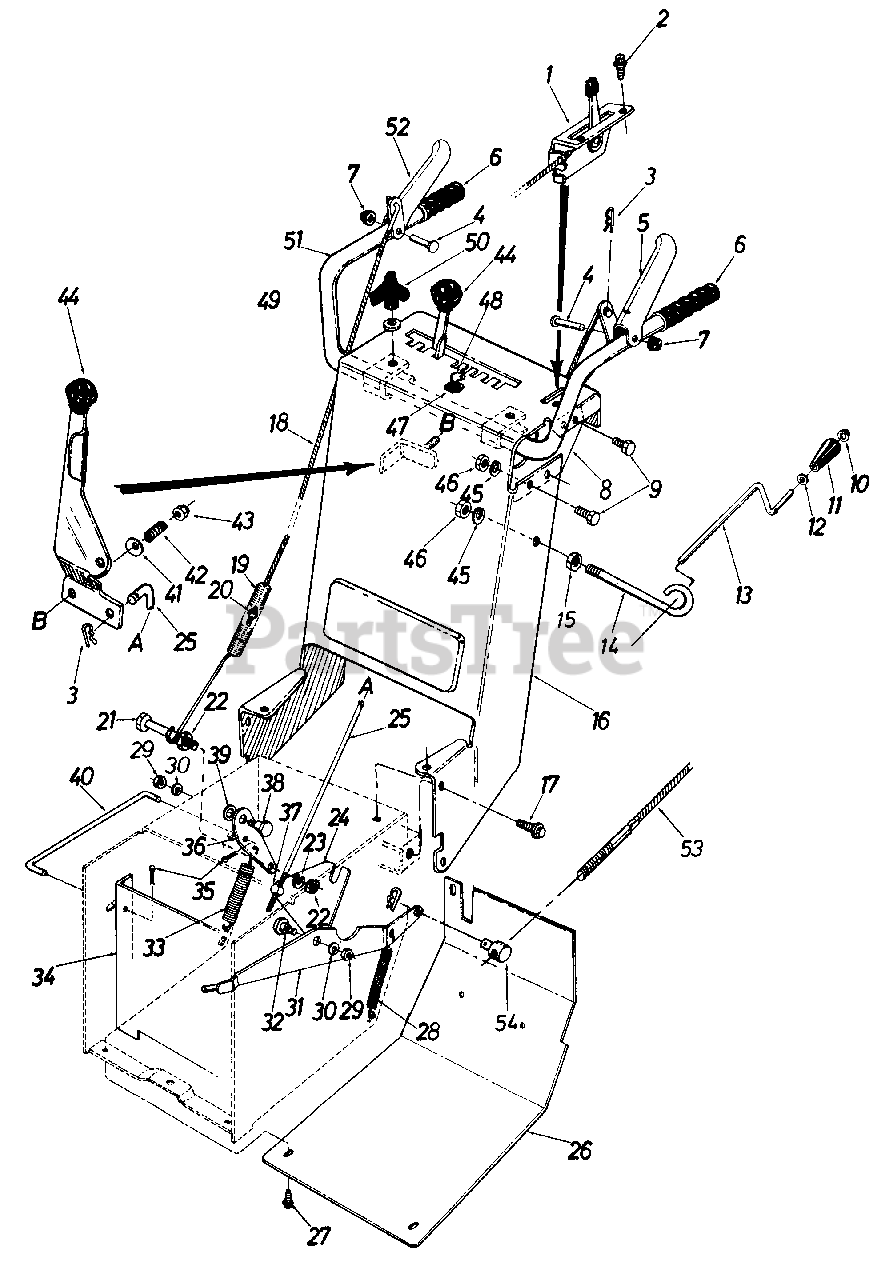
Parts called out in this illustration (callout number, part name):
1	Throttle Control Ass'y. Comp.
2	Hex AB-Tap Scr. #8 x .50" Lg.
3	Hairpin Cotter
4	Clevis Pin .375" Dia. x 1.88" Lg.
5	Auger Clutch Grip Ass'y. - L.H.
6	Grip Handle
7	Push Cap .375 Rod - Black
8	Handle Support Brkt.
9	Hex Bolt 5/16-24 x .62" Lg.
10	Push Nut 3/8" Rod
11	Knob 3/8" I.D.
12	Fl-Wash. .385 I.D. x .62 O.D. .063
13	Chute Crank .38 Dia. x 41" Lg.
14	Chute Control Support Rod
15	Hex Nut 5/16-18 Thd.
16	Handle Panel Ass'y.
17	Hex Wash. Self-Tap Scr. 5/16-24 x .50" Lg.
18	Lockout Cable - 30.5" Lg.
19	Spring .750 O.D. x 5.0" Lg.
20	Hex Ins. L-Nut 1/4-20 Thd.
21	Hex Bolt 1/4-28 x 2.5" Lg.
22	Hex Nut 1/4-28 Thd.
23	L-Wash. 1/4" I.D.
24	Shifting Linkage Brkt.
25	Shifting Rod
26	Frame Cover
27	Hex Wash. Self-Tap Scr. 1/4-20 x .50 Lg.
28	Ext. Spring .38" O.D. x 3.25" Lg.
29	Hex Jam Nut 3/8-16 Thd.
30	L-Wash. 3/8-16 I.D.
31	Auger Clutch Brkt. Ass'y.
32	Shld. Bolt .625" Dia. x .170" Lg.
33	Idler Extension Spring
34	Drive Pulley Support Brkt. Ass'y.
35	Cotterpin 3/32" Dia. x .75" Lg.
36	Drive Clutch Brkt.
37	Ferrule - Engagement
38	Shld. Bolt .625" Dia. x .170" Lg.
39	Bell-Wash. .400" I.D. x 1.13" O.D. x .03" Lg.
40	Rod - Variable Speed
41	Bell-Wash. .40" I.D. x .88 O.D. x .060" Lg.
42	Compression Spring .39" I.D x .88" Lg.
43	Hex Ins. L-Nut 3/8-24 Thd.
44	Shift Handle Ass'y.
45	L-Wash. 5/16" I.D.
46	Hex Nut 5/16-24 Thd.
47	Ignition Switch
48	Ignition Key
49	Bell-Wash. .345" I.D. x .62" O.D. x .063"
50	Three Arm Knob 5/16-18 Thd.
51	Handle Ass'y.
52	Drive Clutch Grip Ass'y. - R.H.
53	Auger Clutch Cable - 36"
54	Adjustment Ferrule
